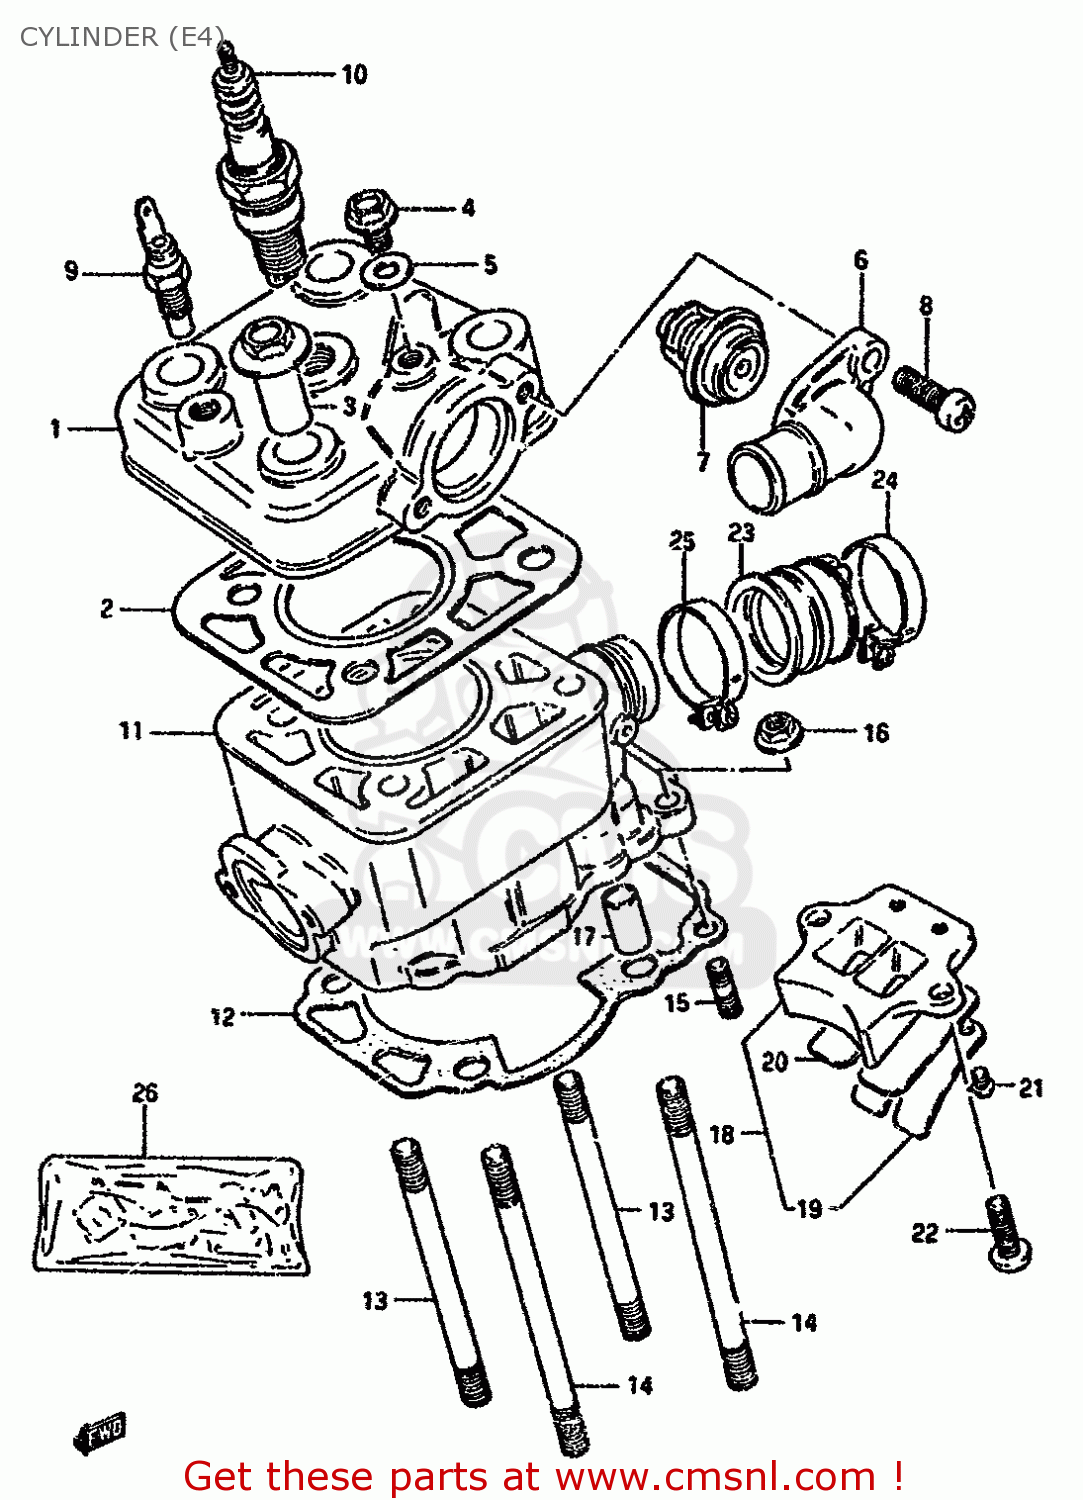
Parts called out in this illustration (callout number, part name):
1	HEAD,CYLINDER
2	GASKET,CYLINDER HEAD (NAS)
3	NUT
4	UNION
5	GASKET(6.2X11X1).2 (NAS)
6	COVER,THERMOSTAT
7	THERMOSTAT,WATER
8	SCREW
9	GAUGE ASSY,WATER TEMP
10	SPARK PLUG BP8ES
11	CYLINDER
12	GASKET,CYLINDER (NAS)
13	STUD BOLT (L:100)
14	STUD BOLT (L:110)
15	STUD 6X16
16	NUT
17	PIN
18	VALVE ASSY,REED
19	STOPPER,REED VALVE
20	VALVE,REED
21	SCREW,REED VALVE
22	SCREW
23	PIPE,INTAKE
24	CLAMP
25	CLAMP
26	GASKET SET
